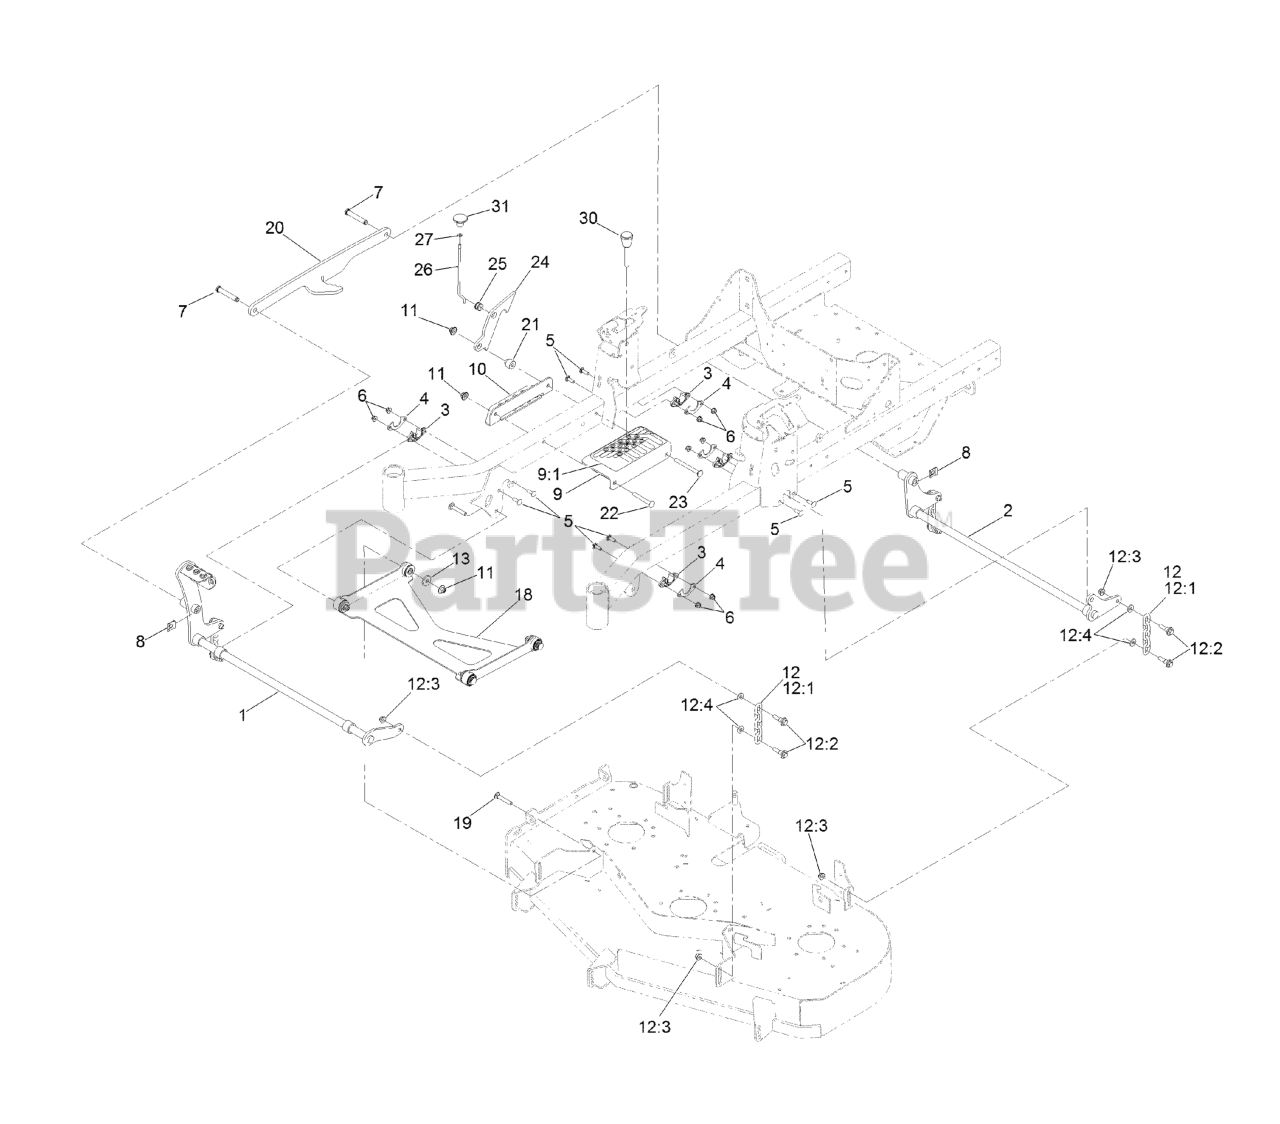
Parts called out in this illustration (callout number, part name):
1	SHAFT-LIFT, DECK
2	SHAFT-LIFT, DECK (REAR)
3	BUSHING-FLANGE
4	GUSSET-LIFT, DECK
5	SCREW-CARR
6	NUT-HF, NI
7	PIN-CLEVIS
8	CLIP-PIN
9	BRACKET ASM
9:1	DECAL-HOC
10	ANGLE-HOC, LOWER
11	Nut-Nyloc 3/8-16 Flg
12	DECK CHAIN ASM
12:1	CHAIN-LIFT, DECK
12:2	BOLT-SHOULDER
12:3	NUT-HF, NI
18	DECK STRUT ASM
19	Bolt-Carriage 3/8-16 X 2 1/4
20	LINK-LIFT
21	SPACER-STEPPED
22	SCREW-CARR
23	SCREW-CARR
24	PLATE-LOCK, TRANSPORT
25	GROMMET
26	ROD-LOCK, TRANSPORT
27	NUT-JAM
30	PIN-HOC
